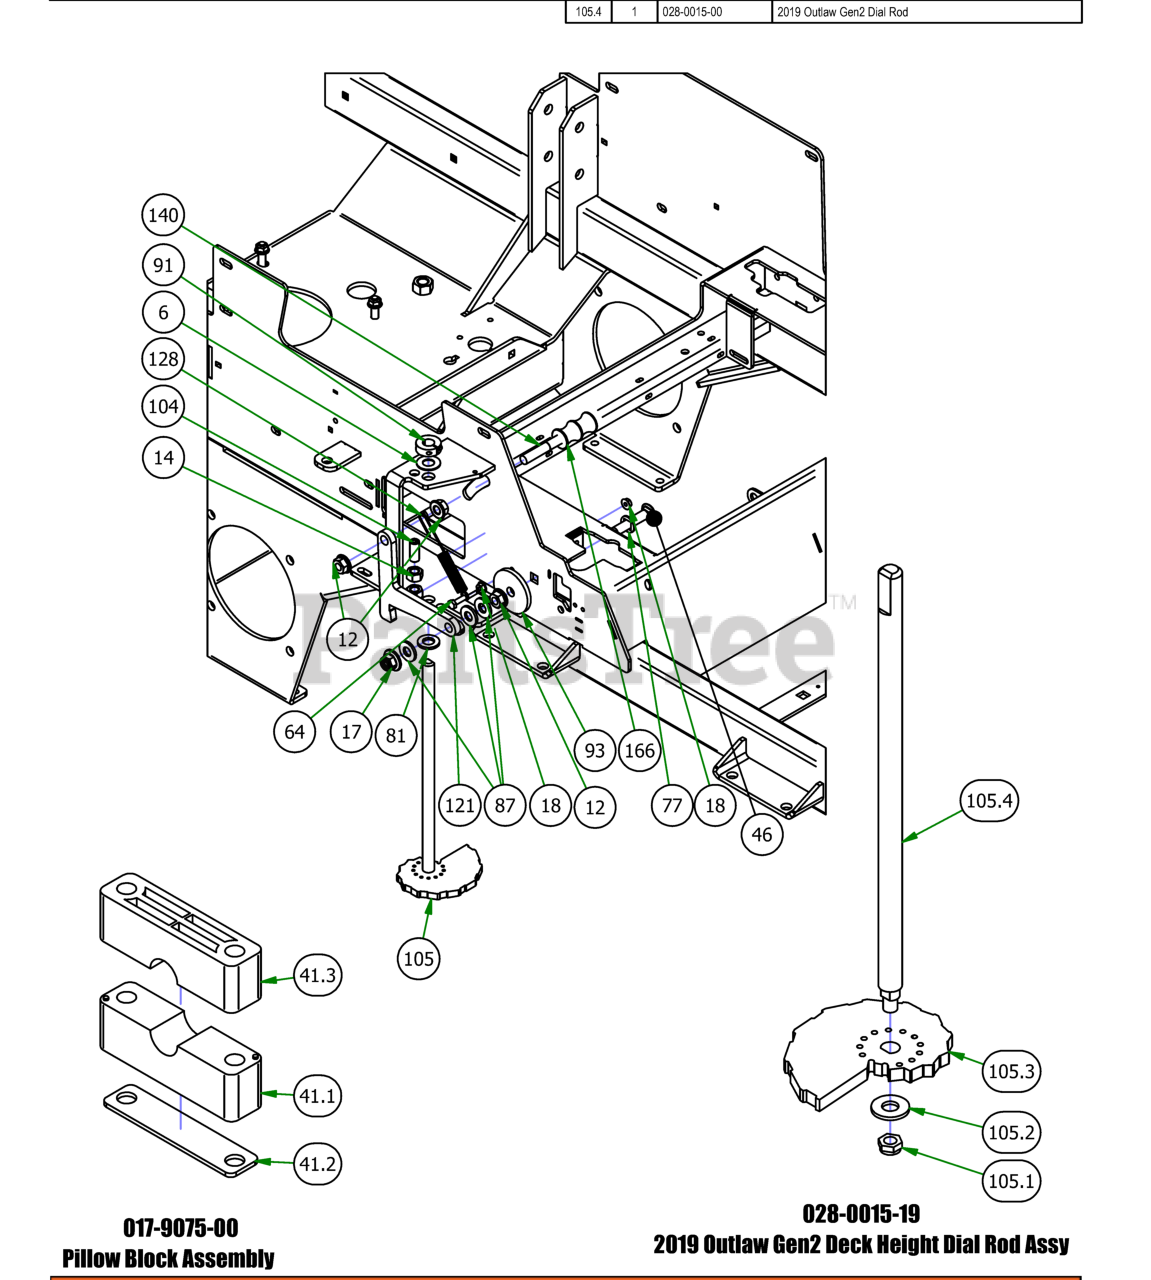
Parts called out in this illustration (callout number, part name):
6	.625 ID x 1.250 OD x .062 THK F/W Nylon
12	1/2" Flange Nut
14	1/2" Hex Nut
17	1/2-13 NYLON INSERT FLANGE LOCKNUT ZINC
18	1/4-20 Hex Flange Nuts Zinc w/Serrations
41.1	Two Piece Pillow Block (Male)
41.2	Two Piece Pillow Block Strap
41.3	Two Piece Pillow Block (Female)
46	1/2 x 2-1/2 Carriage Bolt
64	1/4-20 x 1-1/4 GR 5 Hex Bolt
77	.517 Square Hole Round Washer
81	.630 ID Plastic Washer
87	.505 Nylon Spacer
91	5/8" Split Collar
93	MZ Deck Idler Spacer
104	Dial Rod Plunger
105	2019 Outlaw Gen2 Deck Height Dial Rod Assy
105.1	3/8-24 Nylon Insert jam locknut
105.2	3/8" Flat Washer
105.3	2019 Deck Height Cam
105.4	2019 Outlaw Gen2 Dial Rod
121	2019 Outlaw Deck Travel Lock
128	Brake Spring
140	Seat Bracket Pin
166	Travel Lock Rubber Grip
